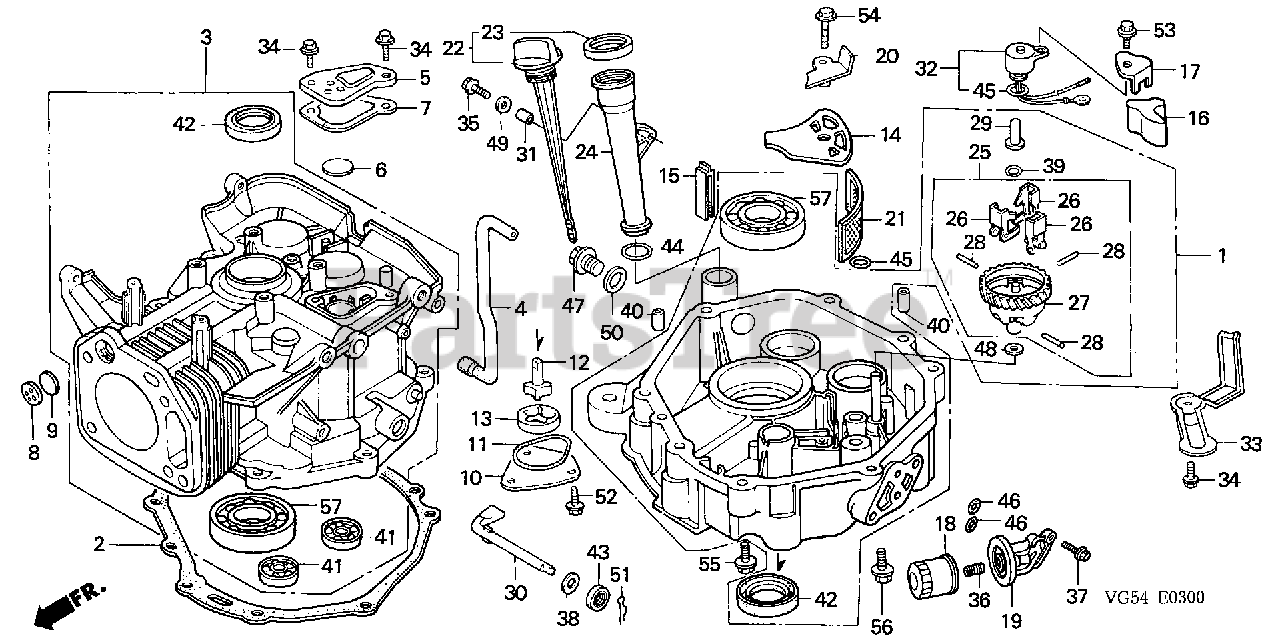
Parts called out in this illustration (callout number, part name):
1	PAN ASSY., OIL
2	GASKET, OIL PAN
3	CYLINDER ASSY.
4	TUBE, BREATHER
5	CAP, BREATHER CHAMBER
6	VALVE, BREATHER
7	GASKET, BREATHER CAP
8	PLATE, ONE-WAY VALVE
9	VALVE, ONE-WAY
10	COVER, OIL PUMP
11	O-RING, PUMP COVER
12	ROTOR (INNER)
13	ROTOR, OIL PUMP (OUTER)
14	PLATE, OIL FILTER
15	RUBBER, OIL RETURN
16	STOPPER, OIL
17	PLATE, OIL STOPPER
18	FILTER, OIL (SOLD INDIVIDUALLY)
19	BASE, OIL FILTER
20	PLATE, SUCTION
21	SCREEN, OIL FILTER
22	CAP ASSY., OIL FILLER
23	GASKET, OIL FILLER CAP
24	EXTENSION, OIL FILLER
25	GOVERNOR ASSY.
26	WEIGHT, GOVERNOR
27	HOLDER, GOVERNOR WEIGHT
28	PIN, GOVERNOR WEIGHT
29	SLIDER, GOVERNOR
30	SHAFT, GOVERNOR ARM
31	COLLAR, EXTENSION
32	SWITCH, OIL LEVEL
33	PROTECTOR, SWITCH
34	BOLT, FLANGE (6X12) (CT200)
35	BOLT, FLANGE (6X35)
36	HOLDER, OIL FILTER
37	BOLT, FLANGE (6X25)
38	WASHER, THRUST (8.1MM)
39	CLIP, GOVERNOR HOLDER
40	PIN, DOWEL (8X12)
41	BEARING, RADIAL BALL (6202)
42	OIL SEAL (35X52X8)
43	OIL SEAL (8X14X5)
44	O-RING (22.5X2.2)
45	O-RING (11.8X2.4)
46	O-RING (11X1.9) (NOK)
47	BOLT, DRAIN PLUG (20MM)
48	WASHER, PLAIN (6MM)
49	WASHER, PLAIN (6MM)
50	WASHER, DRAIN PLUG (20MM)
51	PIN, LOCK (10MM)
52	BOLT, FLANGE (6X12)
53	BOLT, FLANGE (6X16)
54	BOLT, FLANGE (6X25)
55	BOLT, FLANGE (8X40)
56	BOLT, FLANGE (8X60)
57	BEARING, RADIAL BALL (6207)
